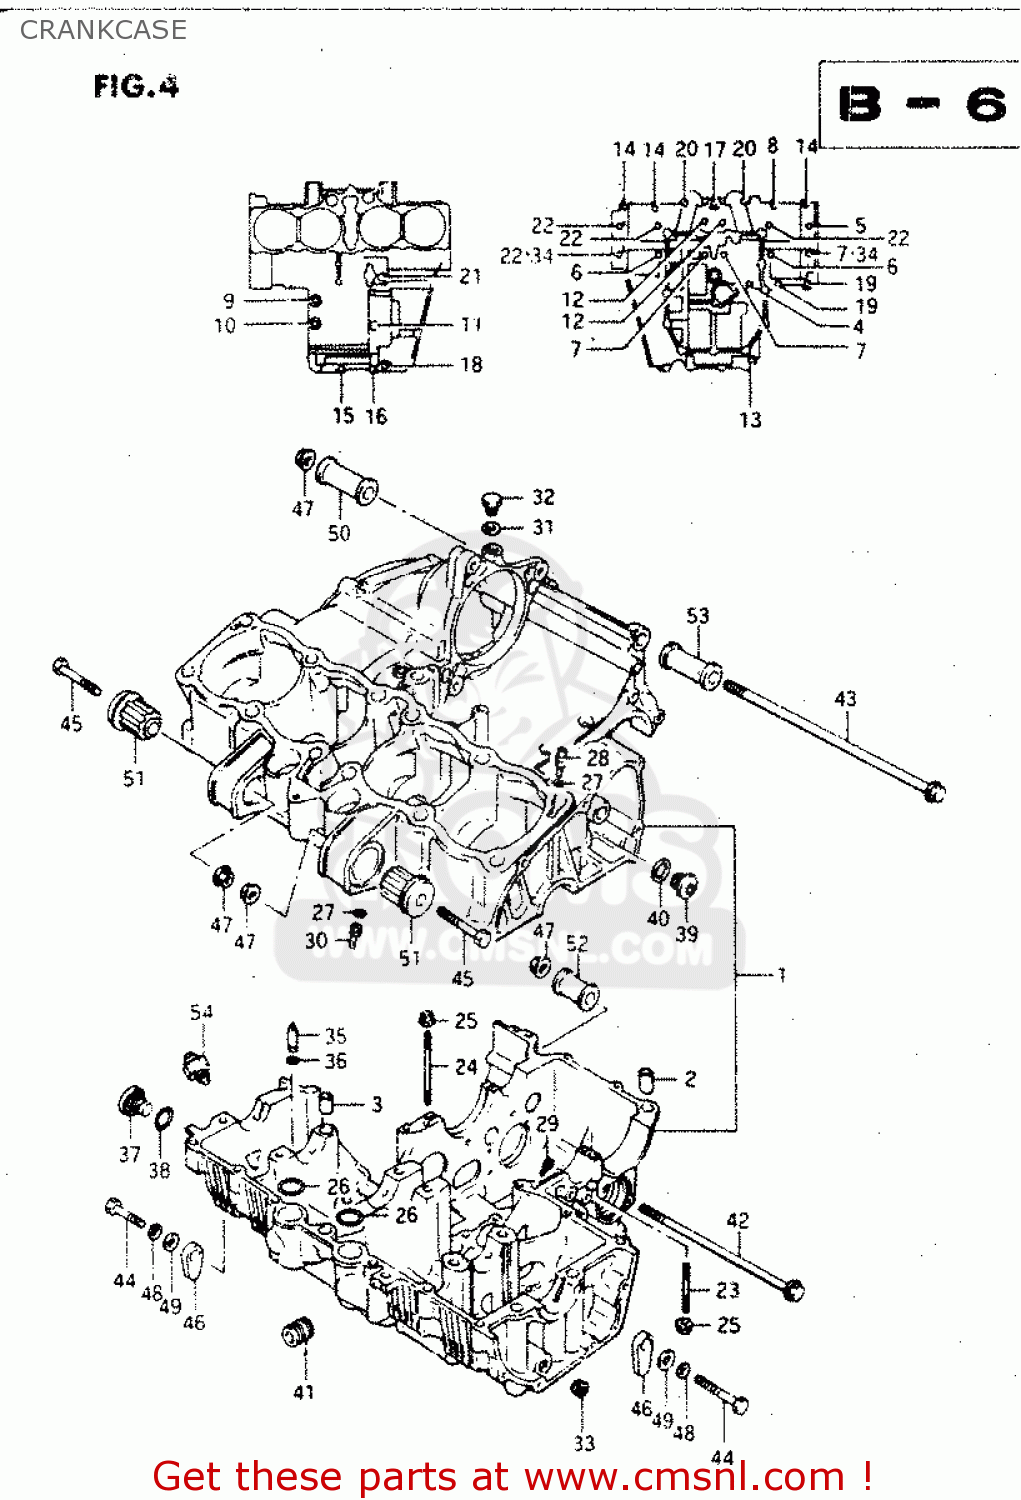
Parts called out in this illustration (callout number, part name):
1	CRANKCASE SET
2	PIN(10.4X13X22)
3	PIN (11X20)(SUS)
4	BOLT(6X105)
5	BOLT(8X105)
6	BOLT(8X125)
7	BOLT(8X115)
8	BOLT 6X35
9	BOLT
10	BOLT
11	BOLT
12	BOLT
13	BOLT 8X60
14	BOLT 6X35
15	BOLT
16	BOLT
17	BOLT 6X50
18	BOLT ,6X60
19	BOLT
20	BOLT
21	BOLT
22	BOLT(8X95)
23	STUD BOLT
24	STUD BOLT
25	NUT
26	O RING(D:2.5,ID:21)
27	O RING(D:1.2,ID:4)
28	JET,AIR
29	JET
30	JET,OIL
31	GASKET(12.1X16.2X3.7) (NAS)
32	PLUG(12X9)
33	PLUG(1/4PT,H:7.5)
34	GASKET(8.5X17X2.3) (NAS)
35	VALVE ASSEMBLY,PISTON OIL
36	O RING(D:1.2,ID:4.7)
37	PLUG
38	O RING(D:2.4,ID:16.8)
39	PLUG
40	GASKET(14X19.2X2) (NAS)
41	UNION,OIL STAND
42	BOLT(10X180)
43	BOLT(10X255)
44	BOLT 10X55
45	BOLT 10X55
46	NUT
47	NUT
48	LOCK WASHER
49	WASHER
50	SPACER,ENGINE MOUNT
51	BUSH,ENGINE MOUNTING
52	SPACER,ENGINE MOUNT
53	SPACER
54	SWITCH ASSEMBLY
